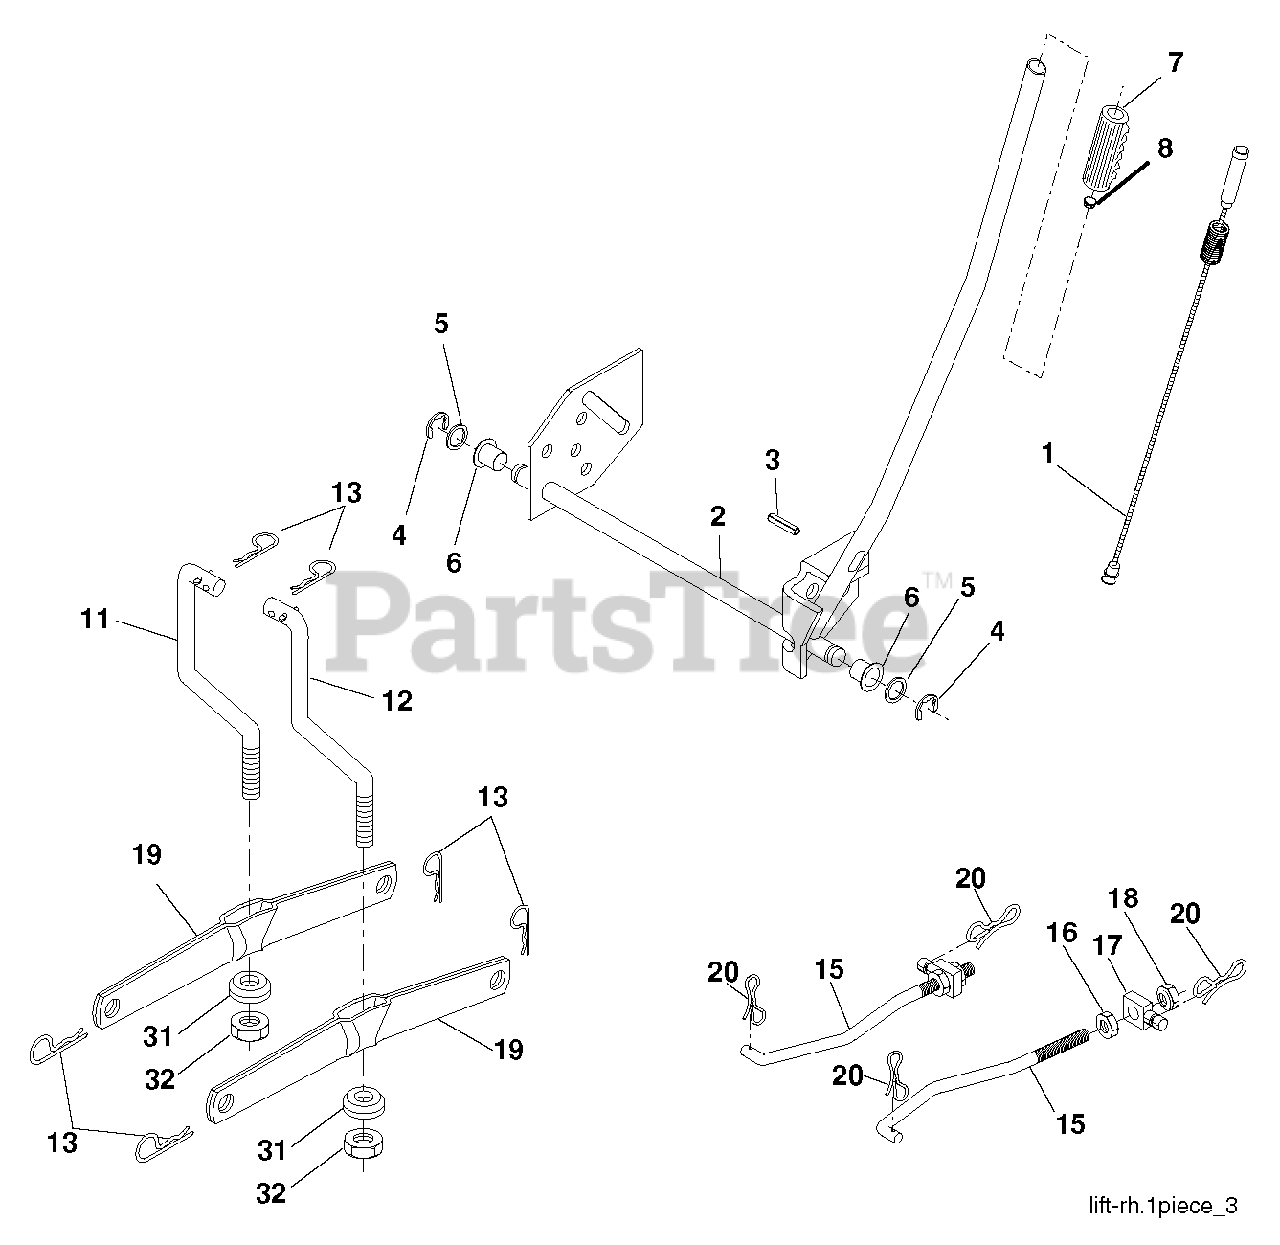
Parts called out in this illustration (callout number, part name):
1	PLUNGER.ASM.LIFT.LVR.BLK.17.32
2	SHAFT ASM R HANDLE
3	PIN GROOVE.
4	RETAINING RING LT
6	BEARING.NYLON
7	GRIP
8	PLUNGER BUT KIT
11	LINK LIFT LH
12	Lift Link Assembly, RH
13	RETAINER-SPRNG RB
15	LINK.SUSPENSION.FRONT
16	NUT.HEX.JAM.1/2-13
17	TRUNNION
18	NUT.LK.W/WSH.1/2.
19	ARM.REAR.SUSPENSION
20	PIN.COTTER.7/16.BOW TI.
31	BEARING.PIVOT.LIFT
32	NUT CROWNLOCK 3/8-24
